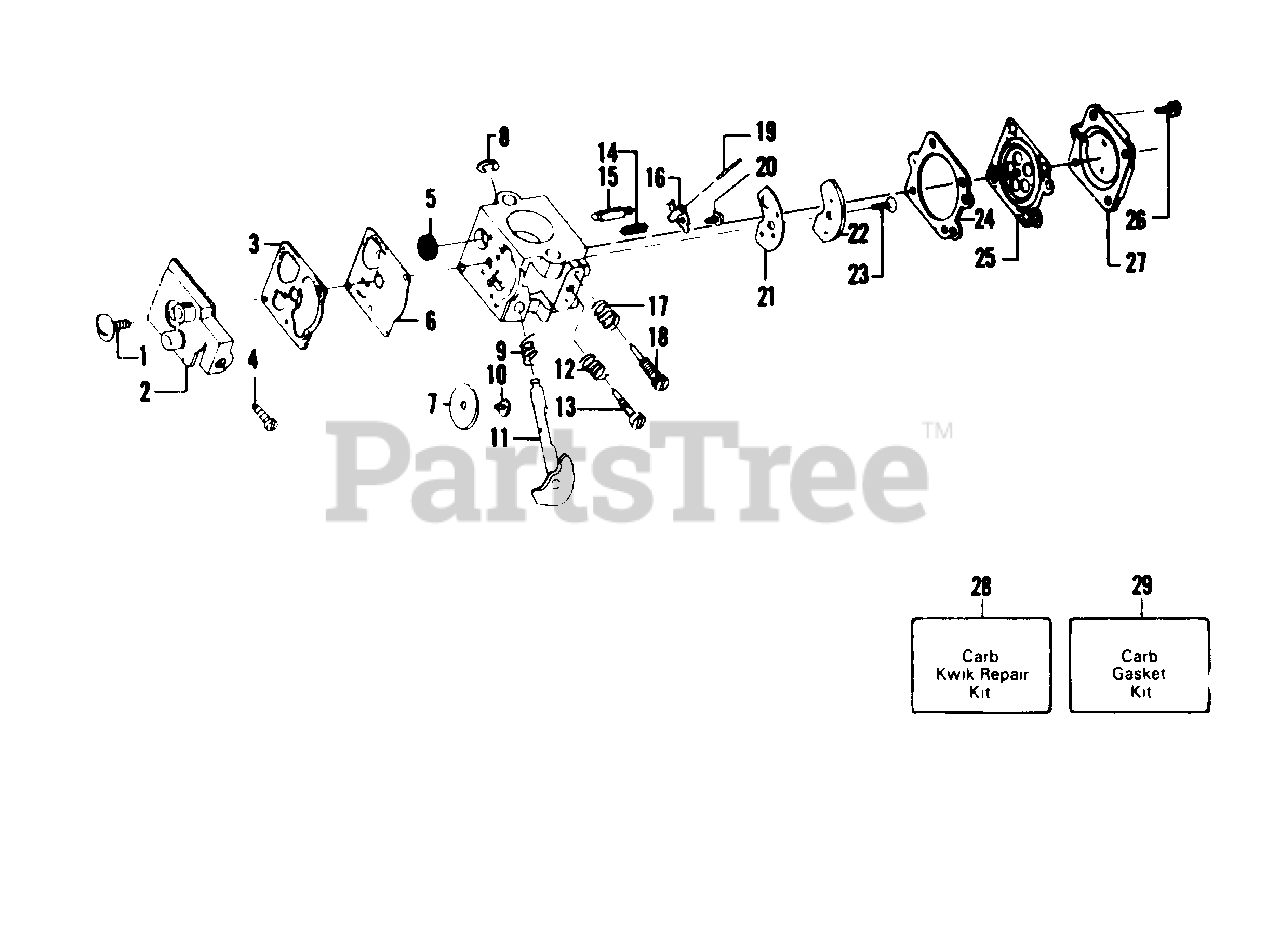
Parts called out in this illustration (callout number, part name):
1	Screw - Pump Cover
2	Pump Cover Ass'y (Incl. #4)
3	Gasket - Pump
4	Screw - Idle Adjustment
5	Screen - Inlet
6	Diaphragm - Pump
7	Valve - Throttle
8	Clip - Throttle Shaft
9	Spring - Throttle Return
10	Screw - Throttle Valve
11	Shaft Assembly - Throttle
12	Spring - Idle Needle
13	Needle - Idle
14	Spring - Metering Lever
15	Valve - Inlet Needle
16	Lever - Metering
17	Spring - Hi Speed Needle
18	Needle - Hi Speed
19	Pin - Metering Lever
20	Screw - Metering Lever Pin
21	Gasket - Circuit Plate
22	Plate - Circuit
23	Screw - Circuit Plate
24	Gasket - Metering Diaphragm
25	Diaphragm Assembly - Metering
26	Screw Assembly - Metering Cover & Throttle Shaft Clip
27	Cover - Metering Diaphragm
28	Kit - Carb. Kwik Repair (Inc. 3,5,6,10,14, 15,16,19,21,23,24,25)
29	Kit - Carb. Gasket / Diaphragm (Inc. 3,6, 21,24,25)
